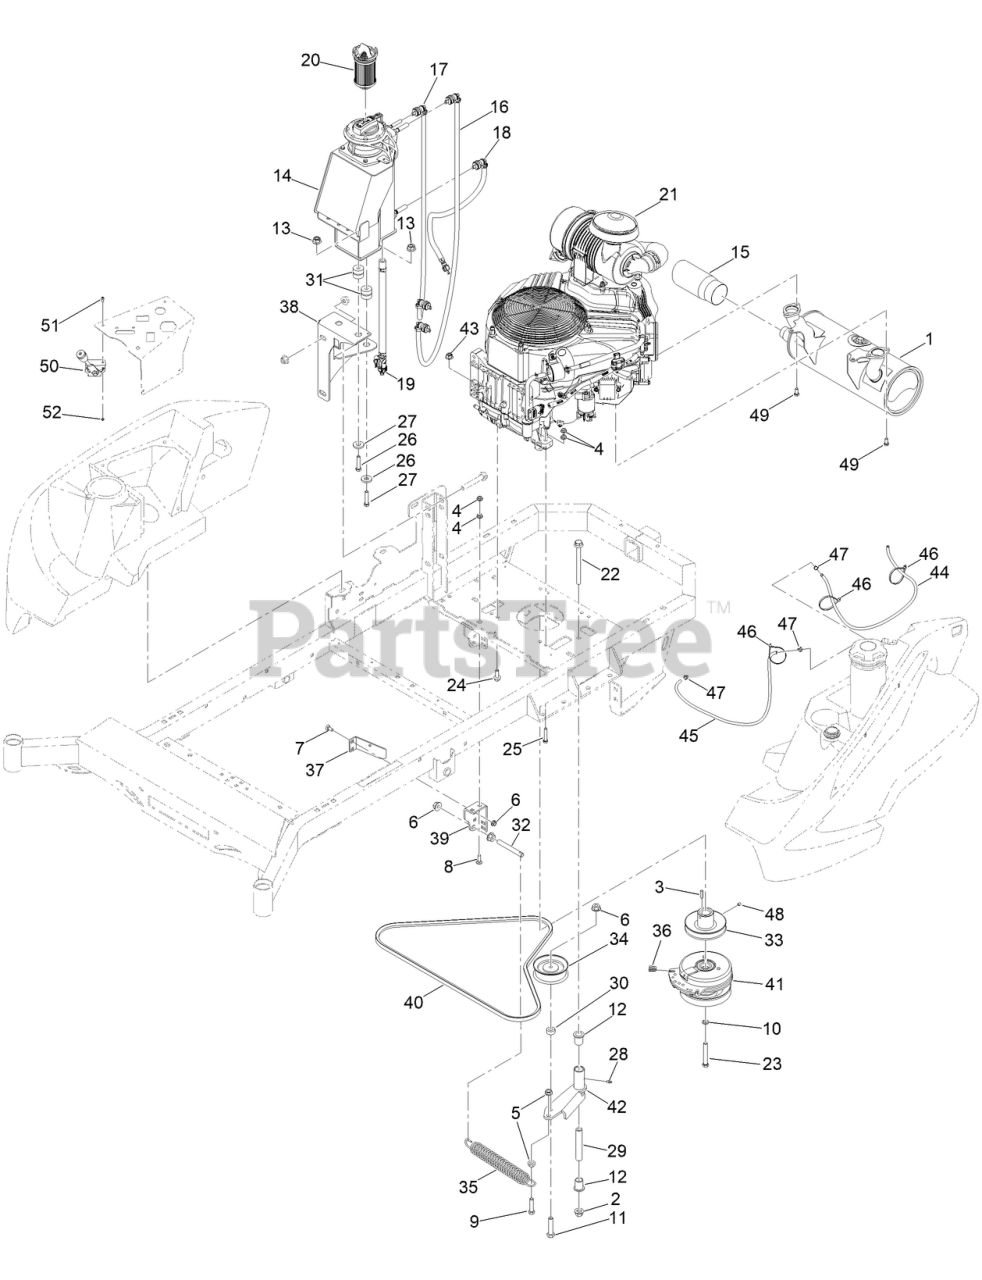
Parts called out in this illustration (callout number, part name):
1	MUFF W/SPARK ARRESTER 6.00INOD1.5IN TP
2	NUT-LOCK
5	NUT-HF
6	NUT-HHF
7	BOLT-CARR
8	5/16-18 X 1-1/4 CARRIAGE BOLT ZC/YEL
9	SCREW-HH
10	WASHER-LOCK
11	SCREW-HH
12	3/4IN ID X15/16IN OD X 1-1/8IN FLNG BUSH
13	3/8-16 NYLON INSERT FLANGE L/NUT YZ
14	VANGUARD OIL GUARD TANK
15	MWR CHROME EXHAUST TIP
16	OIL HOSE ASSY SUPPLY
17	OIL HOSE ASSY SCAVENGE
18	OIL HOSE ASSY VENT
19	OIL FLEX DRAIN HOSE
20	OIL FILTER FOR OIL GUARD
21	VANGUARD 40HP EFI WITH OIL GUARD
22	1/2-13 X 5-1/2 HEX FLANGE BOLT GR 8 ZY
23	7/16-20 X 3 HEX C/S GR 8 ZC YELLOW
24	SCREW-HH
25	5/16-18 X 1-3/4 HEX C/S GR 5 ZINC YELLOW
26	3/8-16 X 1-3/4 HEX C/S GR 2 ZINC
27	1/2 FENDER WASHER 1-1/4IN OD ZINC
28	1/4IN DRIVE TYPE GREASE FITTING YZ
29	MWR INNER IDLER SPACER
30	MWR PULLEY SPACER
31	OIL GUARD ISOLATOR
32	MWR PUMP IDLER SPRING TENSIONER
33	MWR HYDRAULIC PUMP DRIVE PULLEY (B-BELT)
34	4IN DIESEL AND ECONOMY MWER IDLER PULLEY
35	MWR DECK SPRING
36	MWR CLUTCH ROTATION STOP BRKT SLEEVE
37	MWR CLUTCH ANTIROTATION BRKT BLACK
38	MWR OIL GUARD TANK BRKT PAINT
39	MWR PUMP IDLER TENSIONING BRKT BLACK
40	MWR PUMP BELT XD B X 69.40IN EFF LNGTH
41	WARNER PTO CLUTCH
42	4IN PUMP IDLER PULLEY ARM ASSY
43	3/8-16 HEX FLANGE NUT W/SERR ZINC YELLOW
44	MWR FUEL TANK BLACK 3/16IN VENT TUBE 1FT
45	1/4IN SAE J30R7 BULK HOSE 1FT
46	TIE-CABLE
47	1/2IN (#8) HOSE CLAMP
48	5/16-18 X 3/8 SOCKET SET SCREW
49	M8-1.25 X 20MM HEX FLANGE BOLT ZINC 10.9
50	KAWASAKI EFI THROTTLE
51	10-24 X 1/2 SOCKET C/S 18-8 SS
52	NUT-LOCK
